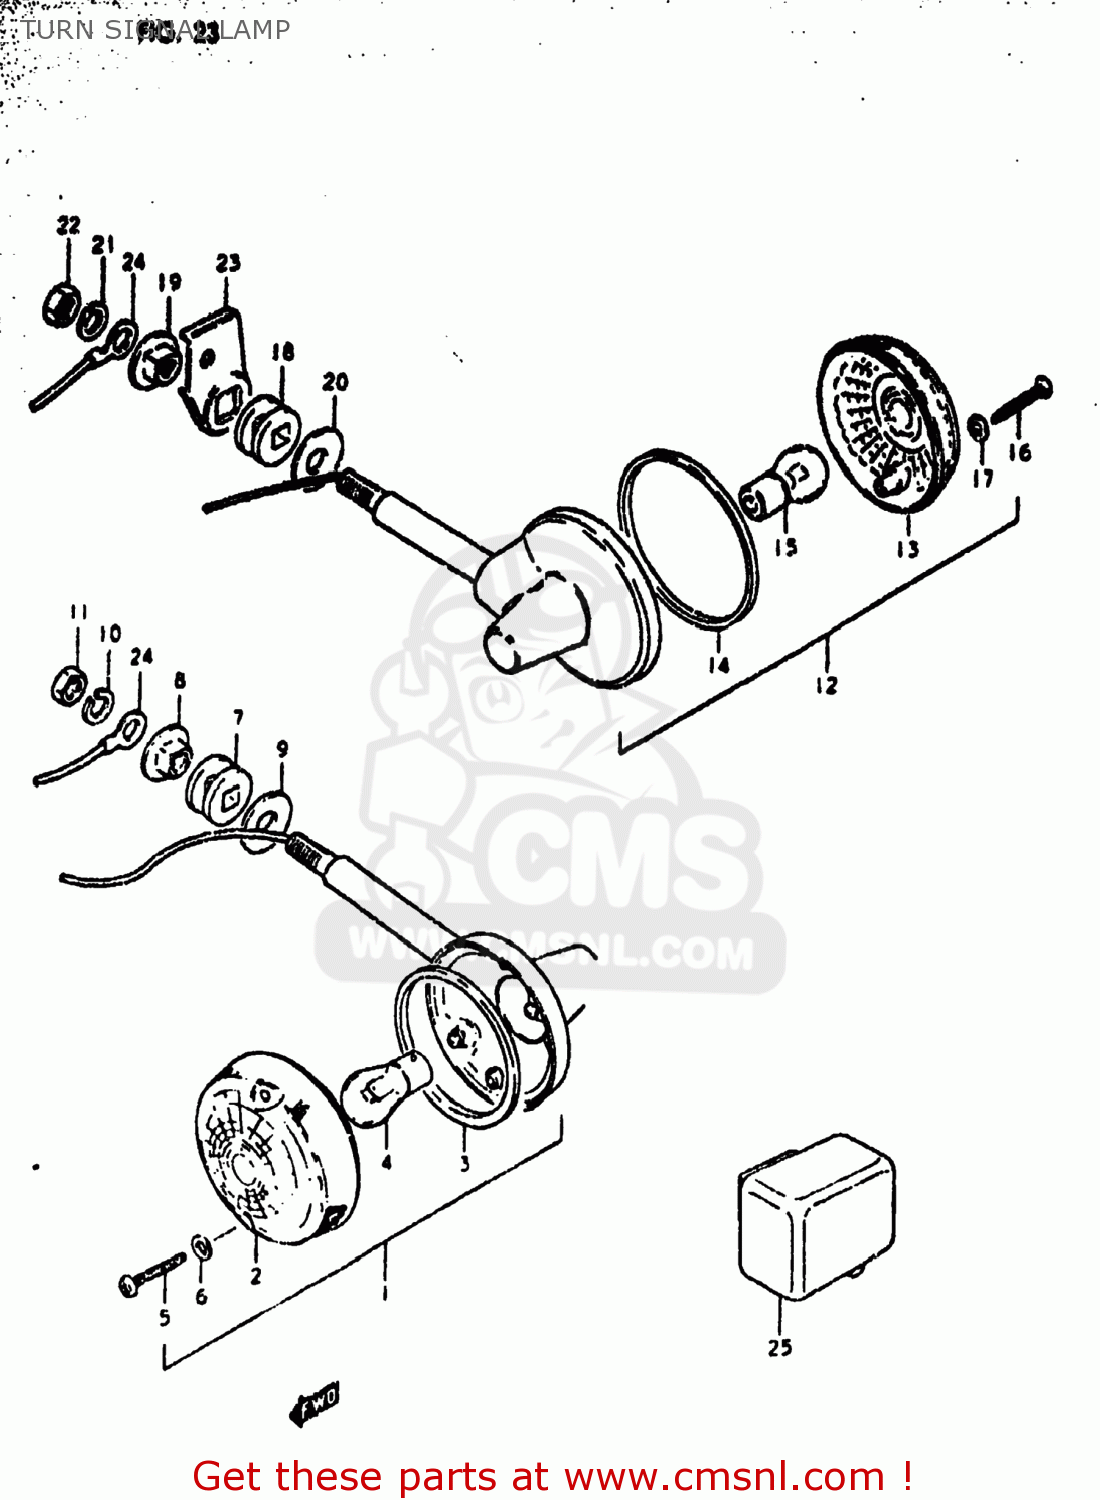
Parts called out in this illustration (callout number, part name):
1	LAMP ASSEMBLY,FRONT TURN SIGNAL
2	LENS
3	GASKET (NAS)
4	BULB(12V23W,STANLEY,A4577A)
5	SCREW
6	GASKET (NAS)
7	CUSHION
8	SPACER,RR TURNSIGNAL LAMP
9	WASHER
10	LOCK WASHER
11	NUT
12	LAMP ASSEMBLY,REAR TURN SIGNAL
13	LENS
14	GASKET (NAS)
15	BULB(12V23W,STANLEY,A4577A)
16	SCREW
17	GASKET (NAS)
18	CUSHION
19	SPACER,RR TURNSIGNAL LAMP
20	WASHER
21	LOCK WASHER
22	NUT
23	BRACKET,RR TURNSIGNAL LAMP,R
24	WIRE
25	RELAY,TURN SIGNAL
